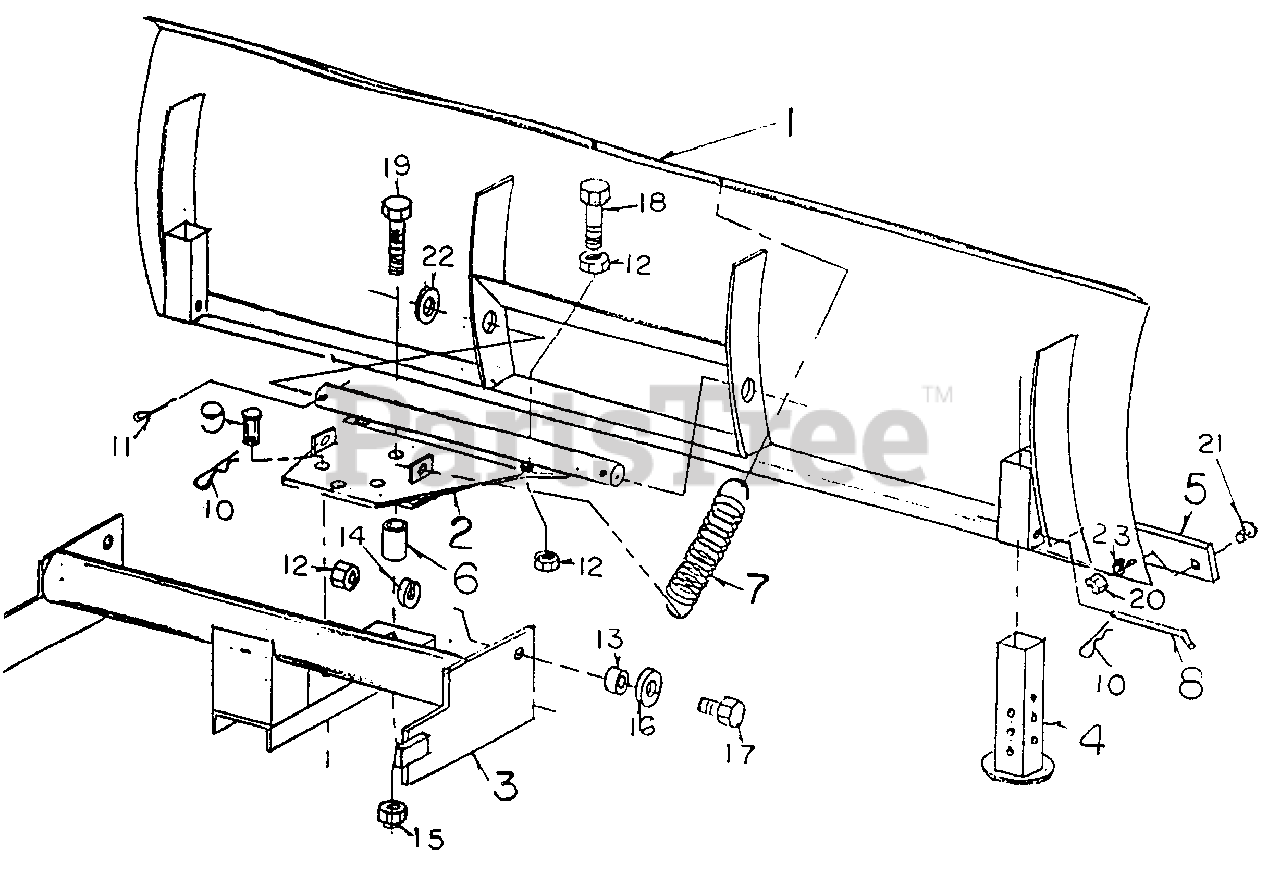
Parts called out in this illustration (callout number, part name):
1	54" Blade
3	54" Blade Mount
5	Replaceable Blade
11	3/16 Cotter Pin
12	1/2-13 Nut
13	Bushing
14	1/2 Lock Washer
15	1/2 Lock Nut
16	1/2 Flat Washer
17	1/2-13 x 1-1/2
18	1/2-13 x 2-1/4
19	1/2-13 x 3
20	5/16-18 Nut
21	5/16-18 x 1 Carg.
23	5/16 Lock Washer
